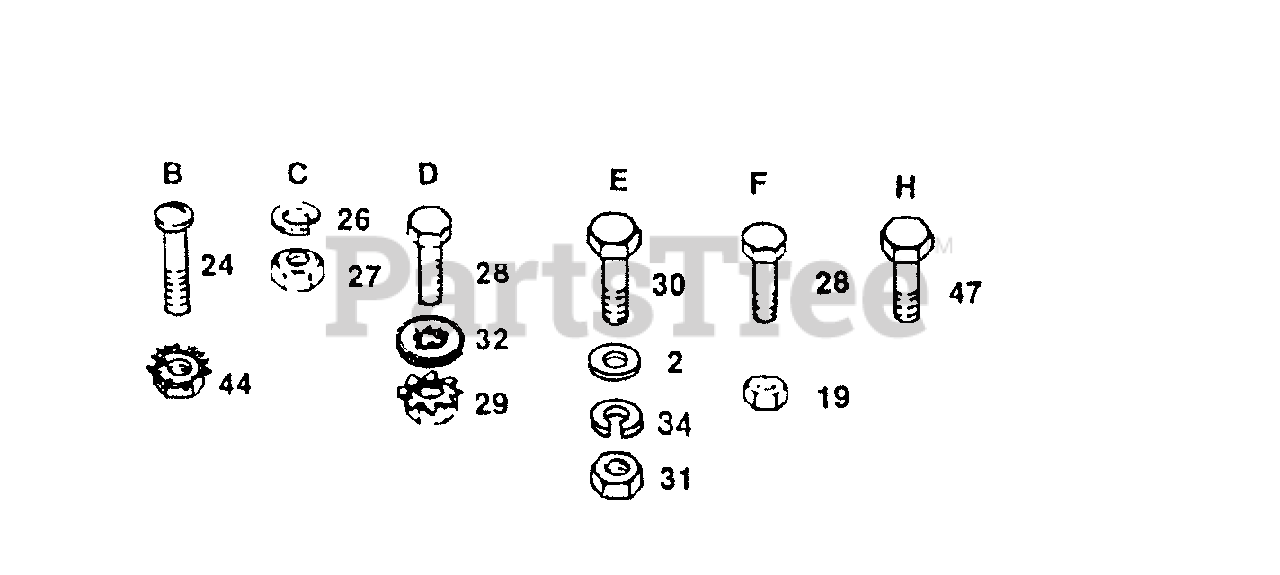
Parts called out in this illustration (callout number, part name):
2	Washer 9/32 x 5/8 x 16 Ga.
19	Nut, Hex 1/4 - 20
24	Screw 10132 x 1/2 Pan Head UNF
26	Lockwasher 1/4
27	Nut, Hex Jam 1/4 - 20
28	Bolt, Hex 1/4 - 20 x 1/2 Gr. 5
29	Nut, Keps, Hex 1/4- 20
30	Bolt, Hex 1/4 - 20 x 3/4
31	Nut, Hex 1/4 - 20
32	Washer, Lock 1/4 - 20 Int. Tooth
34	Washer, Lock 1/4
44	Nut, Keps #10-32 UNF
47	Screw, Hex Tapping #10-24 x 1/2
